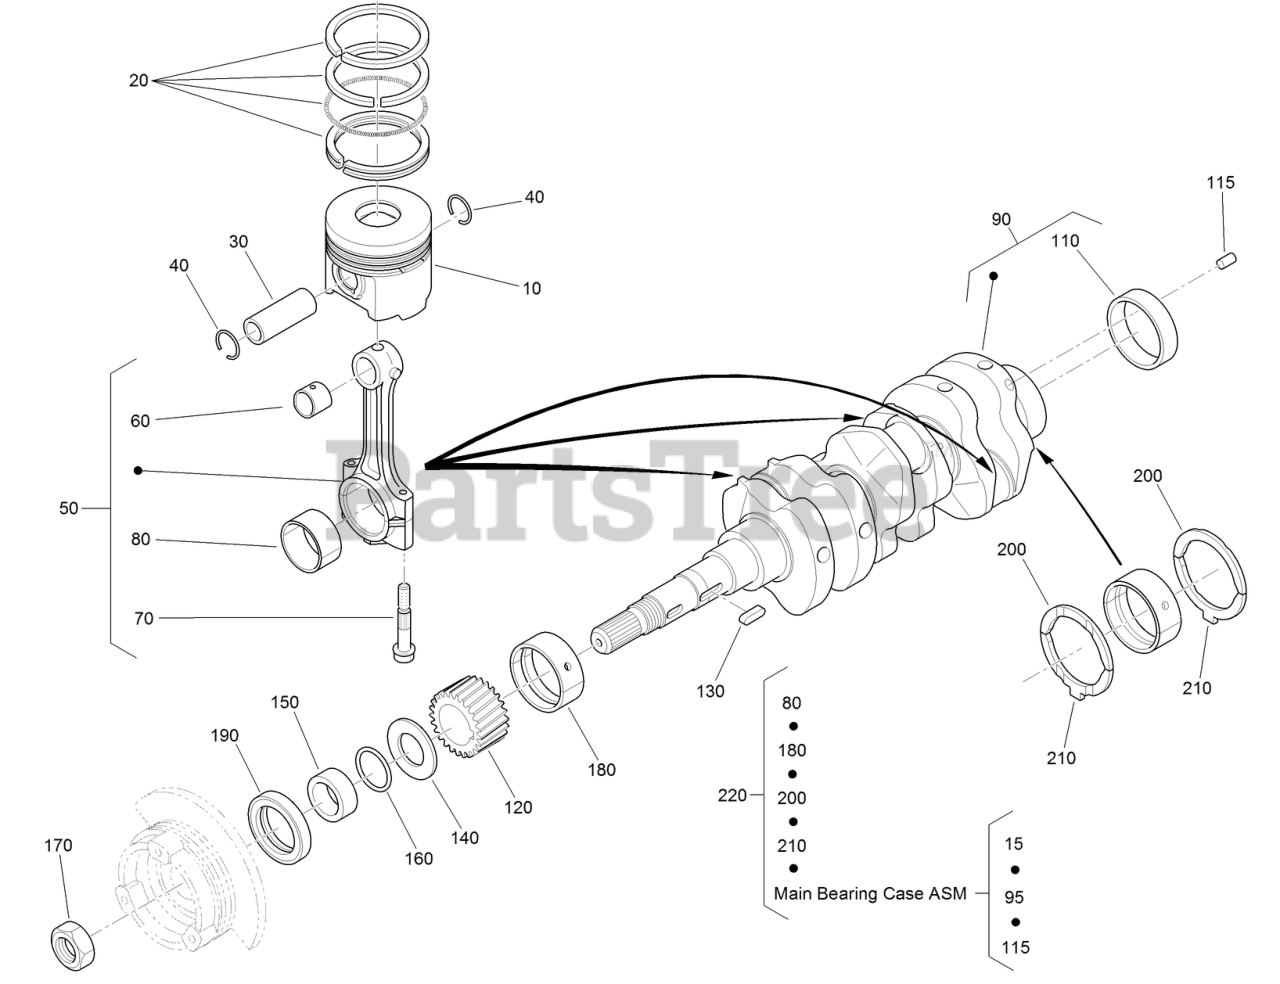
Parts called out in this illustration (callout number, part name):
10	PISTON (05)
20	PISTON RING ASM
30	PIN-PISTON
40	CIRCLIP-INTERNAL
50	CONNECTING ROD ASM
60	BUSHING-PIN, PISTON
70	BOLT-ROD, CONNECTING
80	METAL-CRANKPIN
80	METAL-CRANKPIN (02)
80	METAL-CRANKPIN (04)
90	CRANKSHAFT
110	SLEEVE-CRANKSHAFT
115	PIN-STRAIGHT
120	GEAR-CRANKSHAFT
130	KEY-FEATHER
140	SLINGER-OIL
150	COLLAR-CRANKSHAFT
160	O-RING
170	NUT-CRANKSHAFT
180	METAL-CRANKSHAFT
180	METAL-CRANKSHAFT (-0.20MM)
180	METAL-CRANKSHAFT (-0.40MM)
190	SEAL-OIL
200	METAL-SIDE
200	METAL-SIDE (+0.20MM)
200	METAL-SIDE (+0.40MM)
210	METAL-SIDE
210	METAL-SIDE (+0.20MM)
210	METAL-SIDE (+0.40MM)
220	ENGINE METAL KIT
220	METAL-CRANKSHAFT (-0.20MM)
